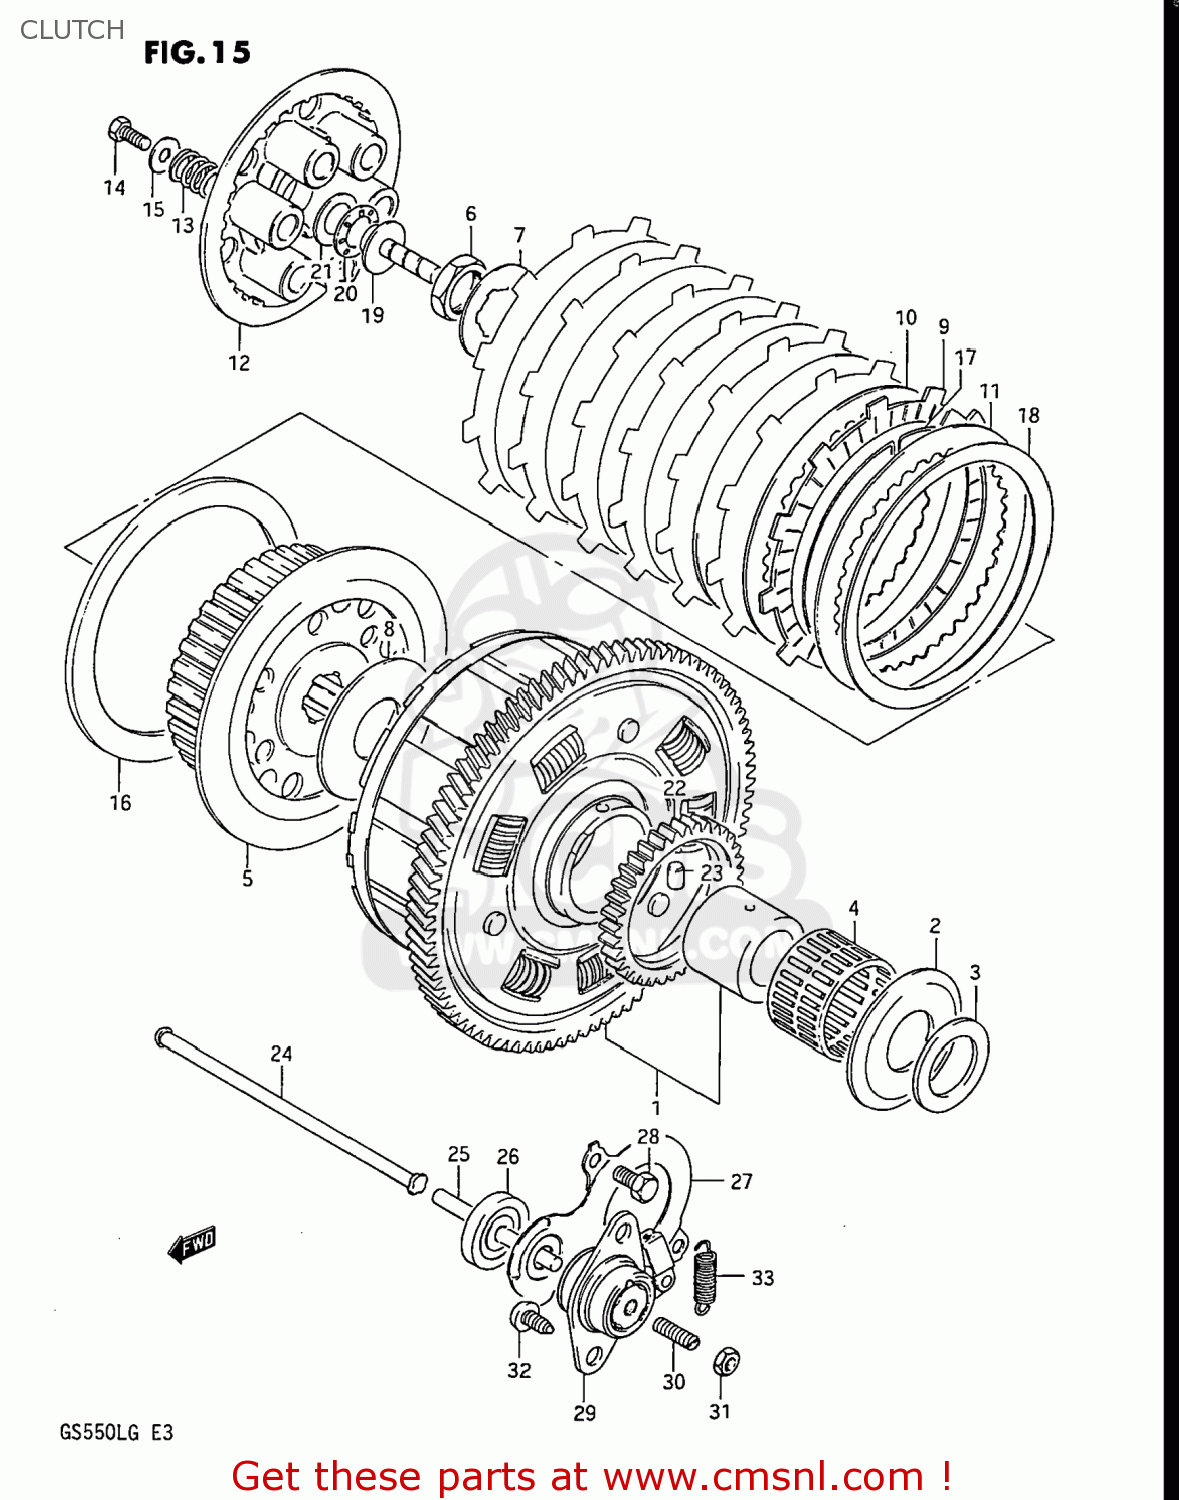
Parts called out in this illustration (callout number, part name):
1	GEAR ASSEMBLY,PRIMARY DRIVE
2	WASHER
3	WASHER
4	BEARING(40X45X32)
5	HUB,CLUTCH SLEEVE
6	NUT
7	WASHER,LOCK
8	WASHER
9	PLATE,CLUTCH DRIVE (NAS)
10	PLATE,CLUTCH DRIVEN (NAS)
11	PLATE,CLUTCH DRIVEN(T:2.0) (NAS)
12	DISC,CLUTCH PRESSURE
13	SPRING
14	BOLT
15	WASHER
16	SEAT,WAVE WASHER
17	RING,STOPPER
18	WASHER
19	PIECE,CLUTCH PUSH
20	BEARING(15X28X2)
21	WASHER
22	GEAR,OIL PUMP DRIVE
23	PIN
24	ROD,CLUTCH PUSH
25	ROD,CLUTCH PUSH,L
26	SEAL,OIL(6X34X7.5)
27	PLATE,CLUTCH PUSH ROD
28	BOLT
29	SCREW ASSY,CLUTCH RELEASE
30	SCREW(6X25)
31	NUT 6MM
32	SCREW
33	SPRING
